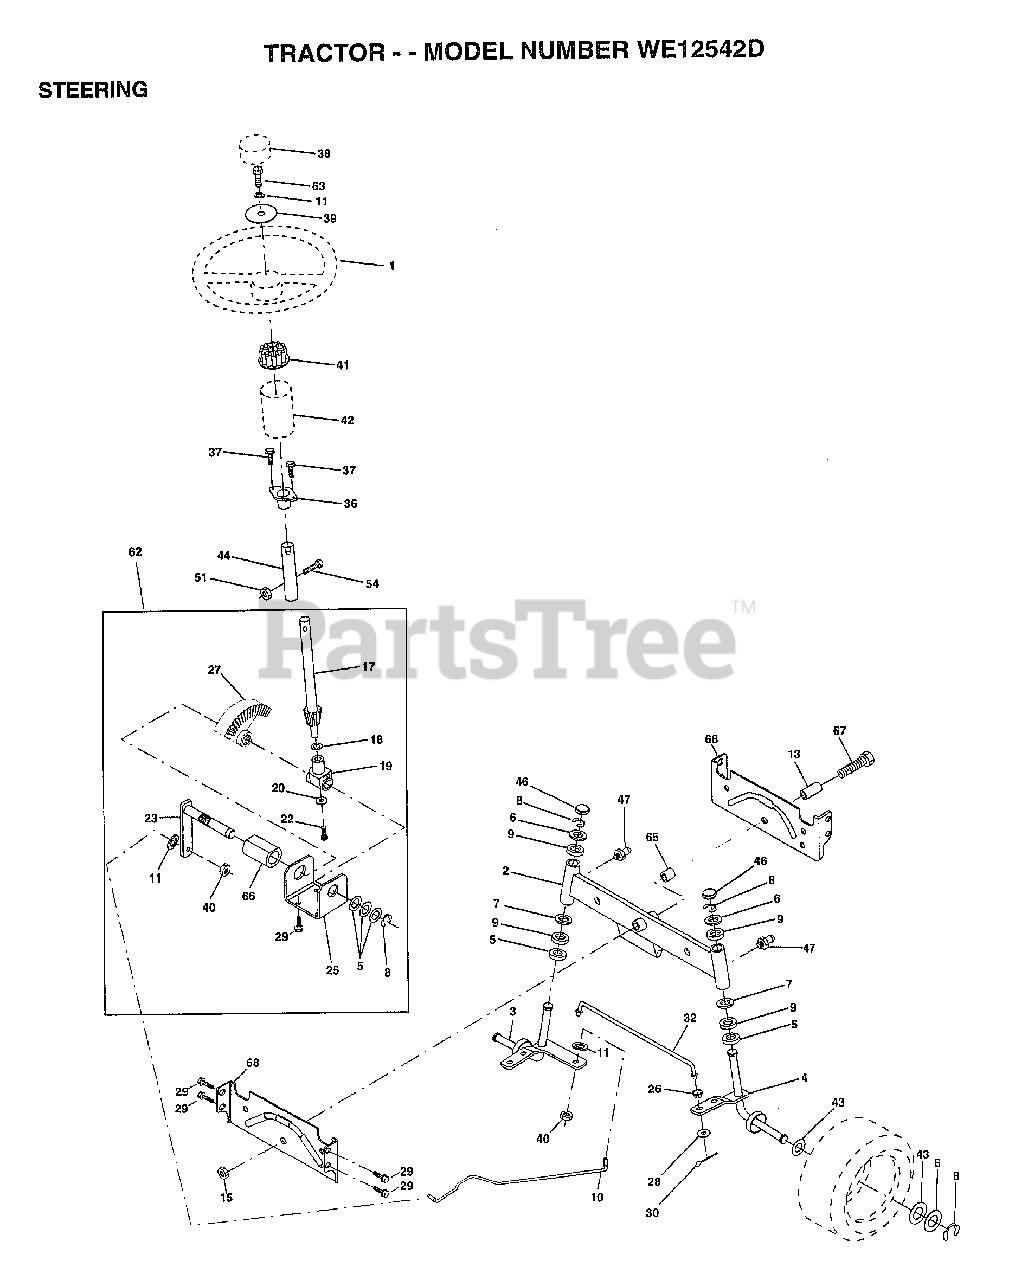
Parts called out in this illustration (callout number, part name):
1	WHEEL STR AYP BLK
2	AXLE ASM
3	SPINDLE.ASM.LH
4	"SPINDLE ASM,RH"
5	WASHER .T
6	WASHER
7	WASHER
8	RING
9	COL. SRTG. BEAR.
10	DRAGLINK-STAMPED
11	LOCKWASHER
13	BEARING AXLE
15	"NUT-LOC,FLANGE LT"
17	SHAFT ASM STEERIN
18	THRUST WASHER
19	SUPPORT.SHAFT
22	SCREW HEX SOC1/4-
25	BRKT-STEERING
26	BUSHING.DRAGLINK
27	GEAR SECTOR
28	WASHER
29	SCREW
30	COTTER PIN
32	TIE ROD
36	BUSHING.STEERING
37	"SCREW-TT,10-32 FL"
38	CAP STEER AYP
39	WASHER T
40	GRIPCO NUT
41	ADAPTER LT
42	BOOT.STEER.PL
43	WASHER
44	EXT SHAFT STEERIN
46	CAP
47	ZERK M
51	NUT
54	BOLT
62	KIT.STEER.ASM
63	BOLT
65	SPACER AXLE
66	"BEARING-ARM,PITMA"
67	BOLT
68	BRACE AXLE
